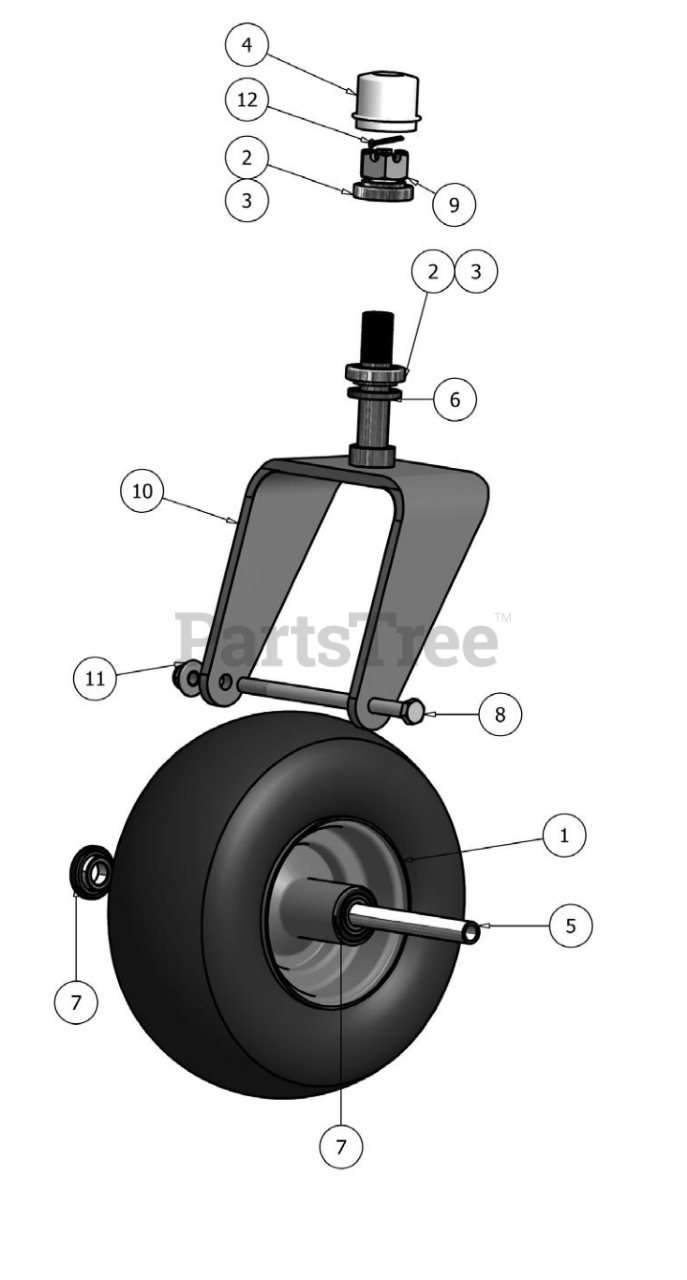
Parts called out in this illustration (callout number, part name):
1	13" x 6.50 6" Tire and
4	Dust Cover
5	Front Wheel Spacer
7	Wheel Bearing
8	1/2" x 9" Bolt
9	1" Fine Threaded Castle
10	Front Fork with Spindle
11	1/2-13 Nylon Flange Nut
12	Cotter Pin
